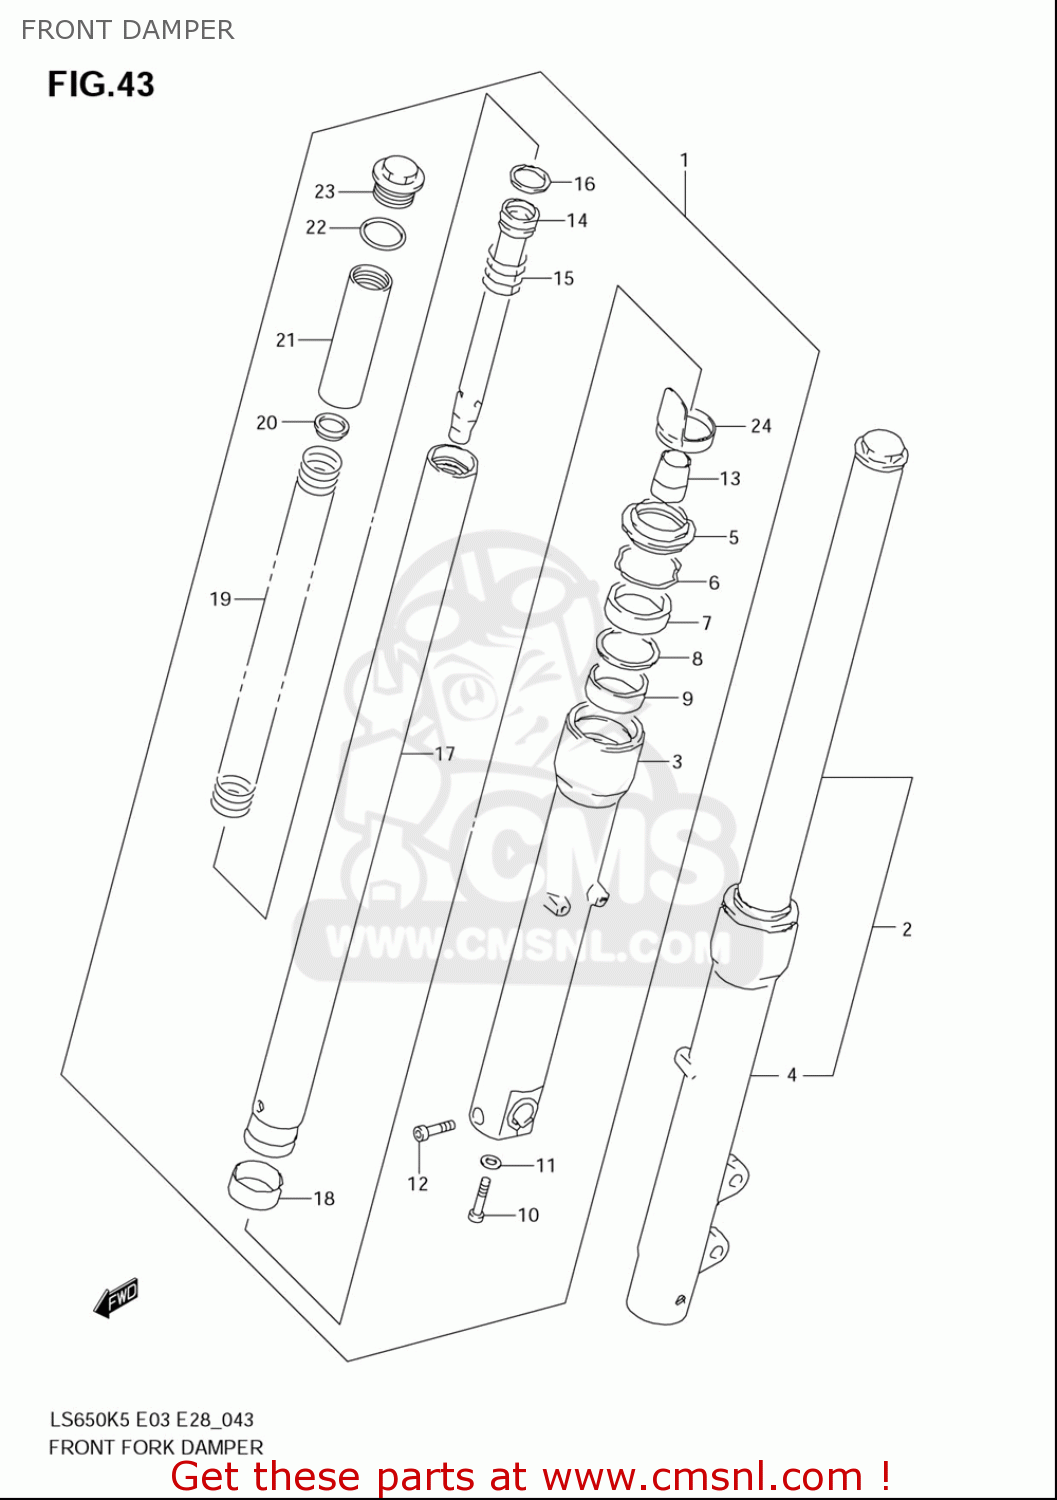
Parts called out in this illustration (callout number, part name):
1	DAMPER ASSY,FR FORK,R
2	DAMPER ASSY,FR FORK,L
3	TUBE,OUTER,R
4	TUBE,OUTER,L
5	SEAL,DUST
6	RING,STOPPER
7	SEAL,OIL
8	WASHER(40X50X2.3)
9	METAL,SLIDE
10	BOLT,FORK CYLINDER(10X25)
11	GASKET (NAS)
12	BOLT
14	CYLINDER
15	SPRING,REBOUND
17	TUBE,INNER
18	PISTON
19	SPRING
20	WASHER
21	SPACER,SPRING
22	O RING
23	CAP
24	PROTECTOR,FR FORK
